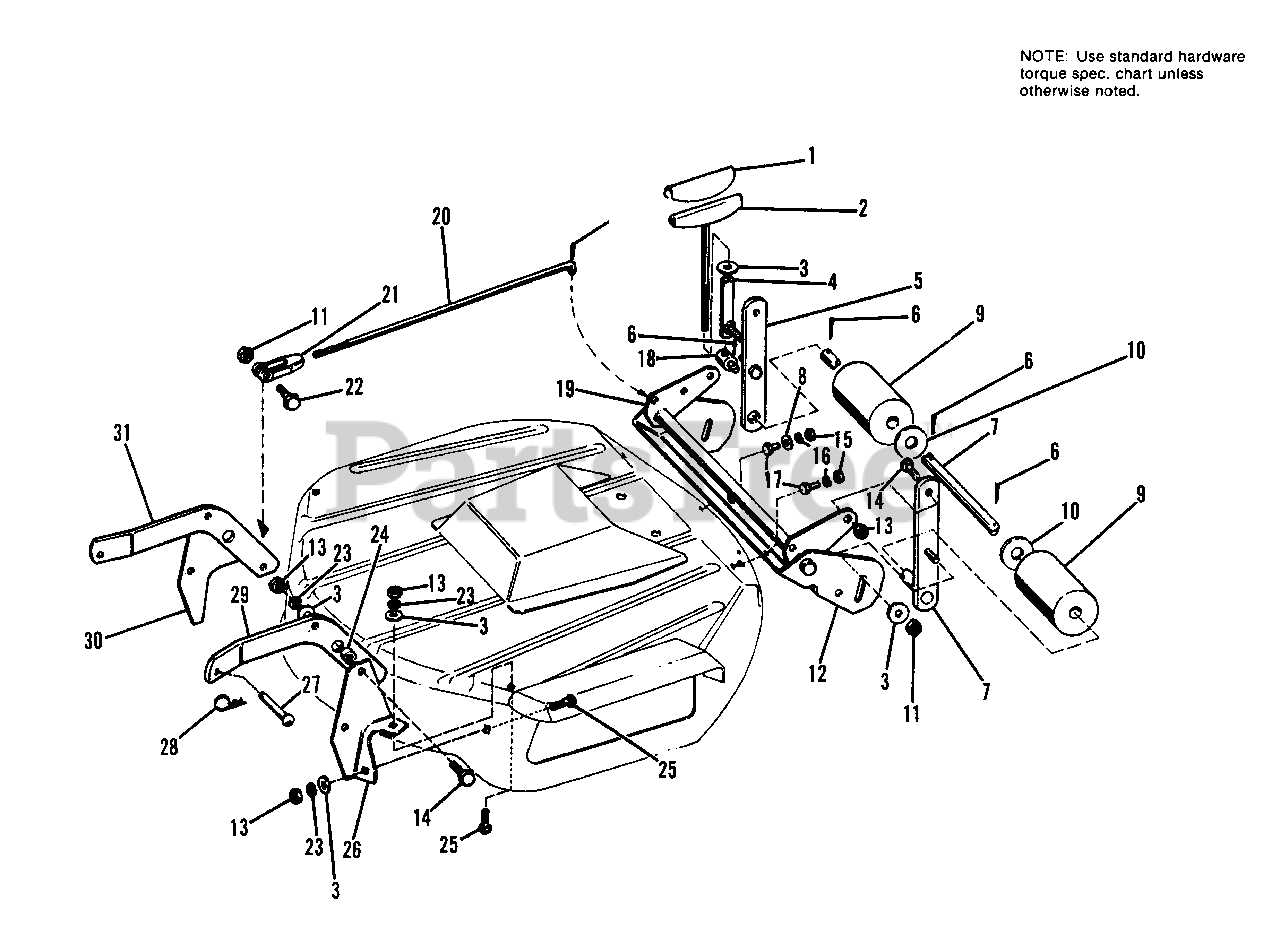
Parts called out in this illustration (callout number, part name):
1	COVER, Handle
2	SCREW ASSY., Adjusting
3	WASHER, Plain, 3/8
4	SOCKET ASSY., Crank
5	BAR ASSY., Roller
6	PIN, Cotter, 3/32 x 3/4
7	ROLLER BAR & SHAFT ASSY.
8	WASHER, Plain, 5/16
11	LOCKNUT, Hex, 3/8-16
12	BRACKET, Roller
13	NUT, Hex, Full, 3/8-16
14	CAPSCREW, Hex Hd., 3/8-16 x 1
15	NUT, Hex, Full, 5/16-18
16	LOCKWASHER, 5/16
17	CAPSCREW, Hex Hd., 5/16-18 x 3/4
19	LEVER ASSY., Rear
20	ROD, Height Adjusting
21	CLEVIS, Adjusting
22	CAPSCREW, Hex Hd., 3/8-16 x 1-1/4
23	LOCKWASHER, 3/8
25	BOLT, Carriage, 3/8-16 x 3/4
26	BRACKET, Front, L.H.
28	CLIP, Spring
29	LEVER, Front, L.H.
30	BRACKET, Front, R.H.
31	LEVER, Front, R.H.
